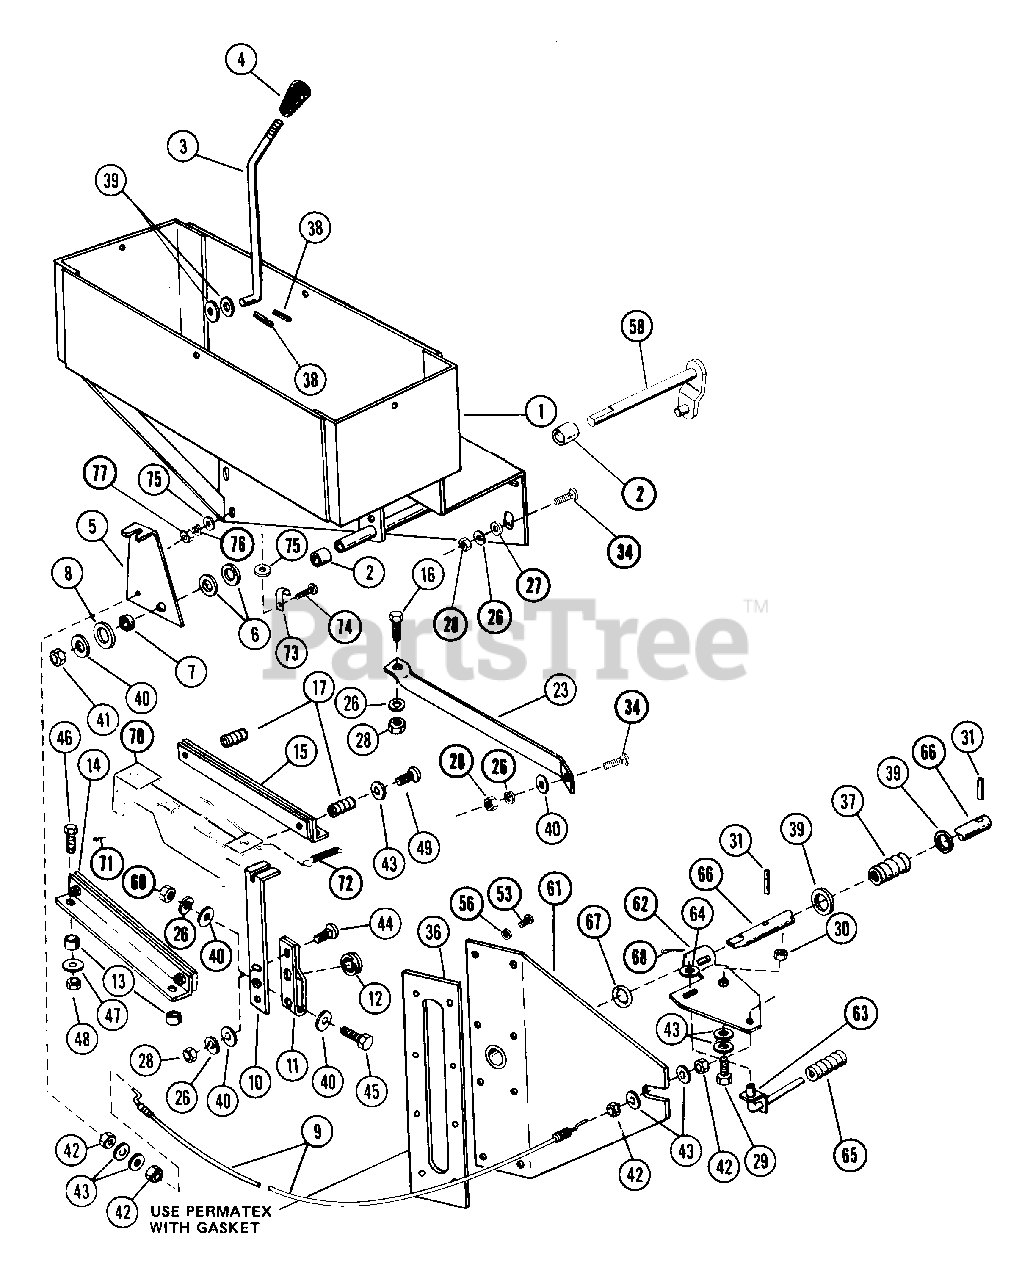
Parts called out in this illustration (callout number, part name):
1	CONTROL BOX
2	BSHG-SLV .625X.750X1.000
3	SHIFT ROD
4	HANDLE
6	WSHR-FL-STL .438X1.125X.19
7	BSHG-SLV .377X.624X.235
8	BELLEVILLE WASHER
13	SPACER .379X.625X.500
14	R. H. FRICTION BRAKE
15	L. H. FRICTION BRAKE
16	BLT-HEX .38-16X.75 PL GR2
17	SG-COMP .093X.59X1.50
26	WSHR-LK .375X.094 MED PL
27	WSHR-FL-STL .438X1.0X.083 PL
28	NUT-HEX .375-16
29	BLT-HEX .31-18X.75 PL GR5
30	NUT-LK .312-18 PL
31	PIN-ROLL .188X1.25
34	BLT-RDHDSQSHNK .38-16X1.00 PL
37	SG-COMP .072X.687X.75
38	PIN-ROLL .188X.88
39	WSHR-FL-STL .531X1.062X.095 PL
40	WSHR-FL-STL.406X.812X.065PL
41	NUT-LK .375-16 PL
42	NUT-JAM .312-24 PL
43	WSHR-FL-STL.344X.688X.065PL
44	BLT-RDHDSQNK .38-16X1.0 PL
45	BLT-HEX .38-16X2.50 PL GR5
46	BLT-HEX .31-18X1.25 PL GR2
47	WSHR-LK .312X.097 PL HVY
48	NUT-HEX .312-18
49	SCR-MCH .31-18X2.50 SLRH PL
53	SCR-TAP 12-24X.50 HWH PL TR
56	WSHR-LK-EXT 12X.025 PL
58	SHIFT SHAFT
60	NUT-HEX .375-16
61	LOCK PIN GUIDE
62	LOCK PIVOT PLATE
63	PIVOT PIN
64	WSHR-FL-STL .344X1.375X.075 PL
65	SG-COMP .092X.77X3.13 WLD 36
66	LOCK PIN
67	O-RING .500X.629X.070
68	PIN-COTR .12X.75 PL
70	SHIFT LOCK
71	PIN COTR .09X.50 PL
72	SG-TENS .035X.45X2.75 WLD 3.5
74	BLT-HEX .38-16X1.00 PL
75	WSHR-FL-STL .38X.875X.083 PL
76	WSHR-LK .375X.094 MED PL
77	NUT-HEX .375-16
